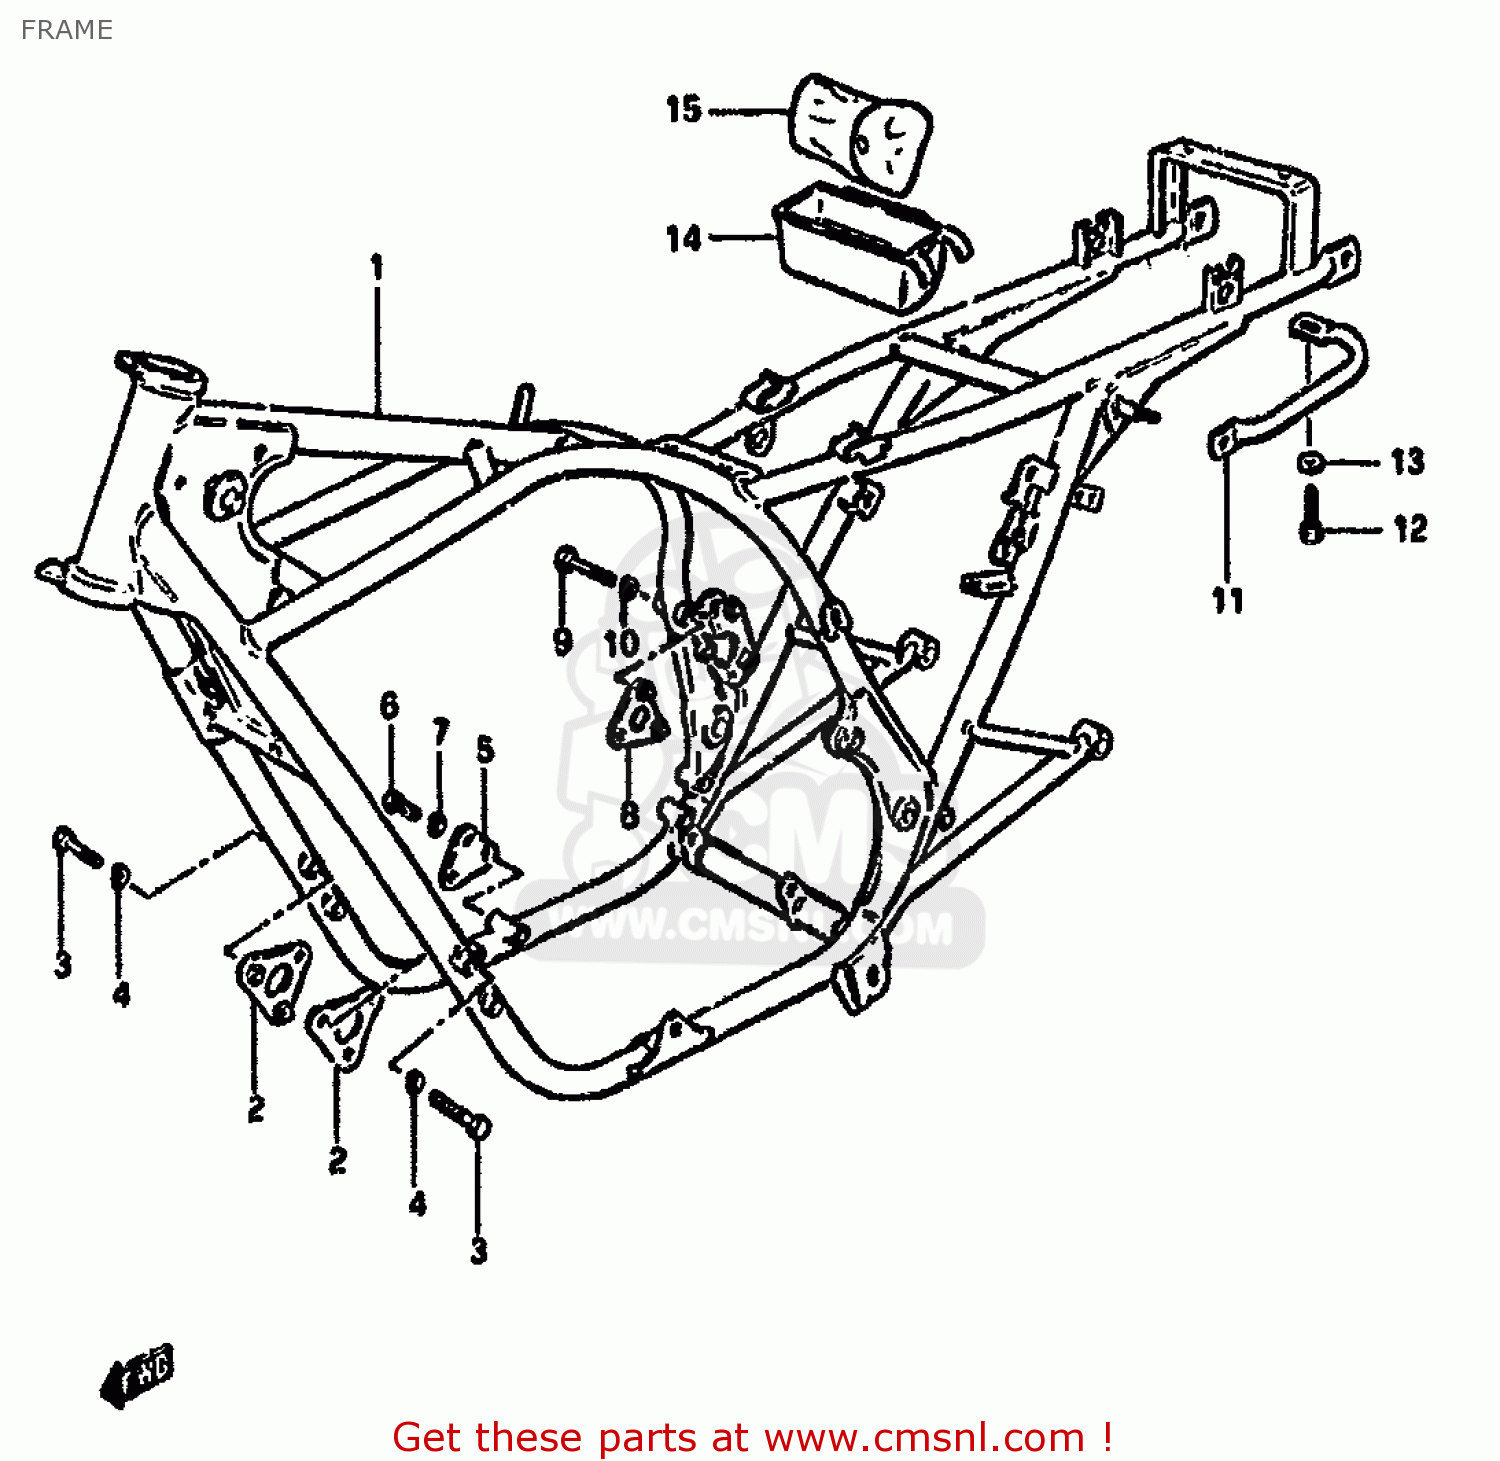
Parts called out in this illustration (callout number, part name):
1	FRAME (BLACK)
2	PLATE,ENGINE MOUNTING
3	BOLT
4	LOCK WASHER
5	PLATE,ENGINE MOUNTING
6	BOLT
7	LOCK WASHER
8	PLATE,ENGINE MOUNTING
9	BOLT 8X55
10	LOCK WASHER
11	GRIP,FRAME HANDLE
12	BOLT
13	WASHER
14	HOLDER,TOOL
15	TOOL SET
